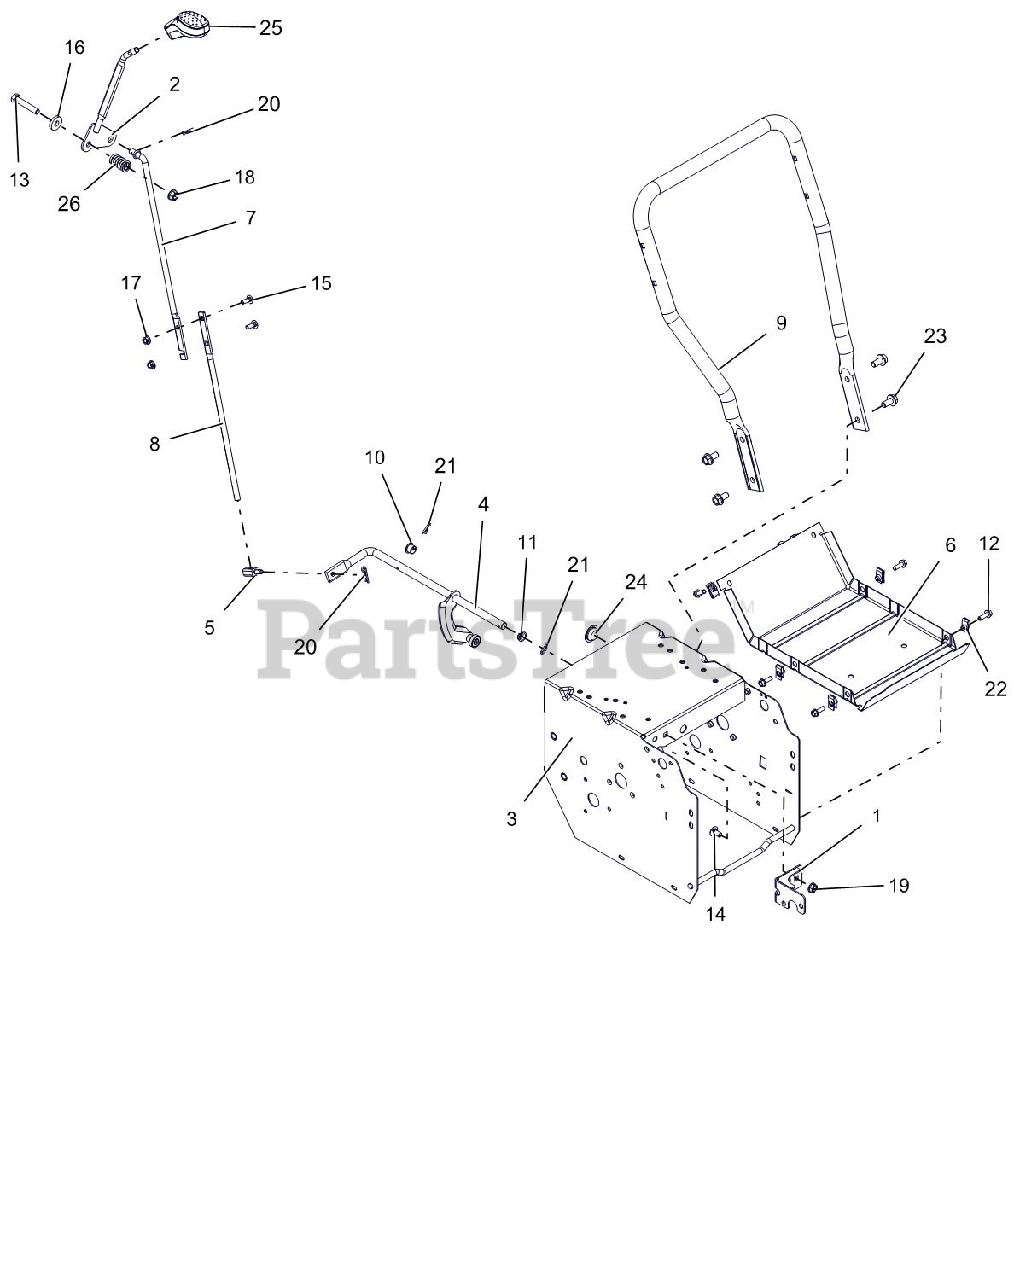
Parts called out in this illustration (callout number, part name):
1	WMT-FRAME BRACKET
2	LEVER, CONTROL-SHIFT(WELDMENT)
3	WELDMNET, FRAME-DELUXE 16"
4	ARM, SHIFT-SMALL DASH (ASSY)
5	PIVOT,SHIFT ROD .375-16(TRUNN)
6	COVER, BOTTOM
7	ROD, SHIFT - UPPER
8	ROD, SHIFT - LOWER(SMALL DASH)
9	HANDLEBAR, LOWER - SM DELUXE
10	BUSHING, POLYLINER-.50 SPLIT
11	BUSHING, POLYLINER-.50 SNAPIN
12	BLT-HEX .25-20X.75 HWH YZ GR5
13	BLT-HEX .38-16X2.00 GR5 YWZC
14	BLT-RHDSSQNK .31-18X.62 G5YZ
15	BLT-RDHDSQNK .25-20X.75 G5YZ
16	WSHR-FL-STL .406X1.00X.188 YWZ
17	NUT-LK-CTR-FLG .25-20 YWZC
18	NUT-LK-TOP-FLG .38-16 YWZC
19	NUT-LK-TOP-FLG .31-18 YWZC
20	PIN-HAIR INT .08X.18X1.18 YWZC
21	CLIP, SPRING
22	NUT-RTNR .25-20X.56
23	BLT-SERHFWH .38-16X.75 YWZC
24	PLUG, HOLE - .875" NYLON
25	KNOB, CONTROL, DASH
26	SG-COMP .125X.781X1.250
